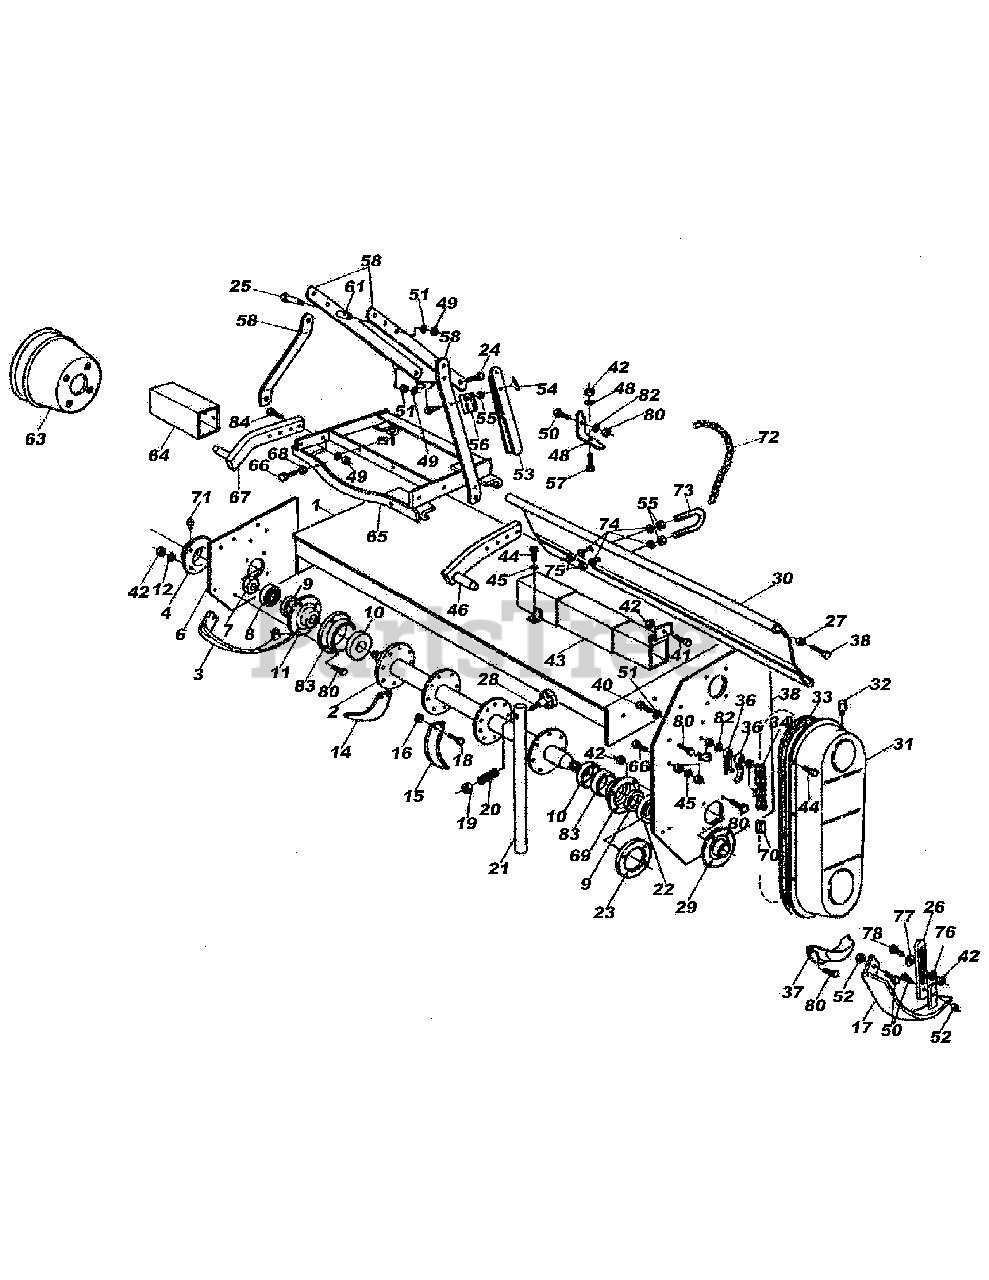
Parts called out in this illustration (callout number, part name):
1	Main Frame
2	Rotor
3	Skid - Right
4	Bearing Cover - Right
6	Right Side Panel
7	Saftey Nut
8	Bearing 6306
9	Oil Seal 40.60.10
9	Oil Seal 40.56.8
10	Dirt Shield
11	Bearing Cover Inner
12	Lock Washer M10
13	Nut M10
14	C-Knife Right
15	C-Knife Left
16	Nut M12
17	Skid - Left
18	Bolt M12 x 30
19	Nut M14
20	Jack Stand Spring
22	Bearing 6307
23	Disk with Holes
24	Bolt M12 x 90
25	Bolt M12 x 100
26	Serrated Ajustment Arm
27	Nut M16
28	Bolt M114 x 70
29	Bearing Cover Left
30	Tailgate
31	Chain Case Cover
32	Breather Cap
33	Gasket
34	Chain ASA 80 x 36
35	Chain Tensioner
36	Chain Tensioner Spring
37	Chain Pan Protection
38	Bolt M16 x 70
39	Left Side Panel
40	Bolt M10 x 60
41	Bolt M10 x 45
42	Nut M10
43	Telescopic Cover
44	Bolt M10 x 20
45	Lock Washer M10
46	Lower Hitch Plate Left
47	Bolt M10 x 55
48	Chain Hitch
49	Nut M12
50	Bolt M10 x 30
51	Lock Washer M12
52	Nut M10
53	Ratchet Arm
54	Wing Nut M8
55	Nut M8
56	Locking Cover
57	Bolt M10 x 55
58	Top Hitch Support
59	Top Hitch Arm
60	Bolt M10 x 25
61	Spacer
63	Protective Cover
64	Right Protection
65	Side Shift Complete
66	Bolt M12 x 60
67	Lower Hitch Plate Right
68	Bolt M10 x 50
69	Nut M12
70	Chain Link Inner
70	False Chain Link
71	Grease Fitting
72	Chain
73	U Bolt
74	Flat Washer 8mm
75	Nut M8
76	Washer with Hole
77	Washer with Thread
78	Bolt M10 x 50
78	Bolt M10 x 60
80	Nut 10mm
82	Washer
83	Ext. Cover
84	Bolt M12 x 60
84	Bolt M12 x 50
